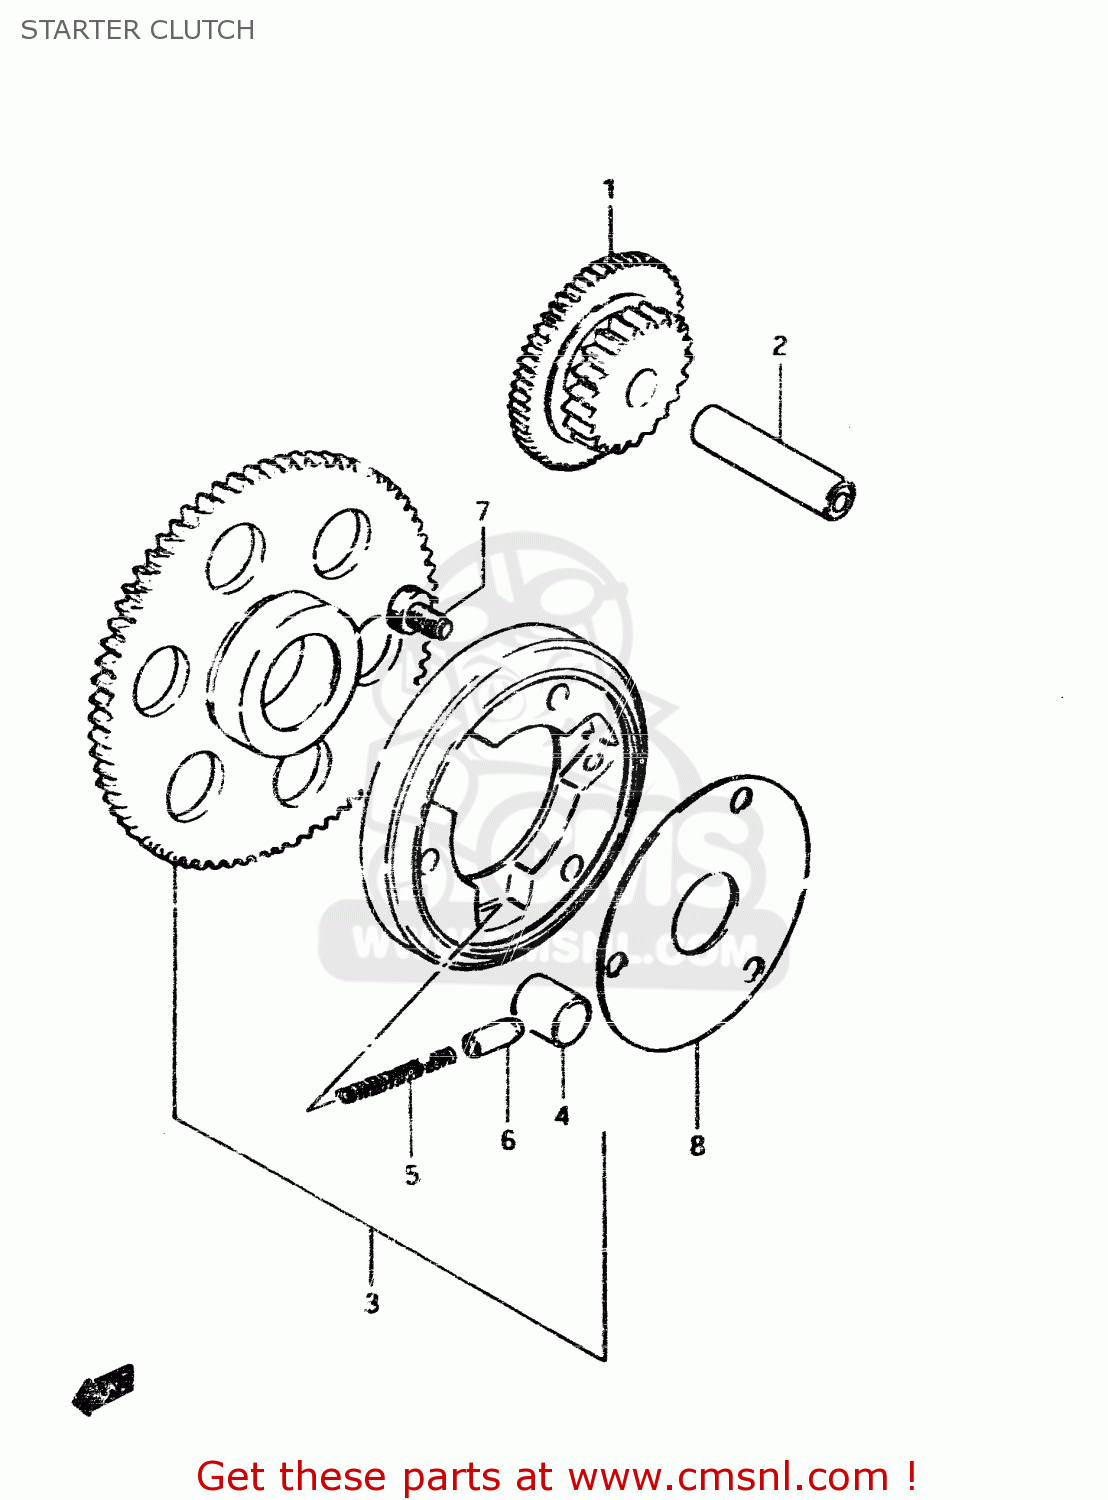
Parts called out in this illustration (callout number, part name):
1	GEAR,STARTER IDLE
2	PIN(7.4X13X56)
3	CLUTCH SET,STARTER
4	ROLLER(15X13)
5	SPRING
6	PIECE,PUSH
7	BOLT
8	SHIM,STARTER CLUTCH HUB
